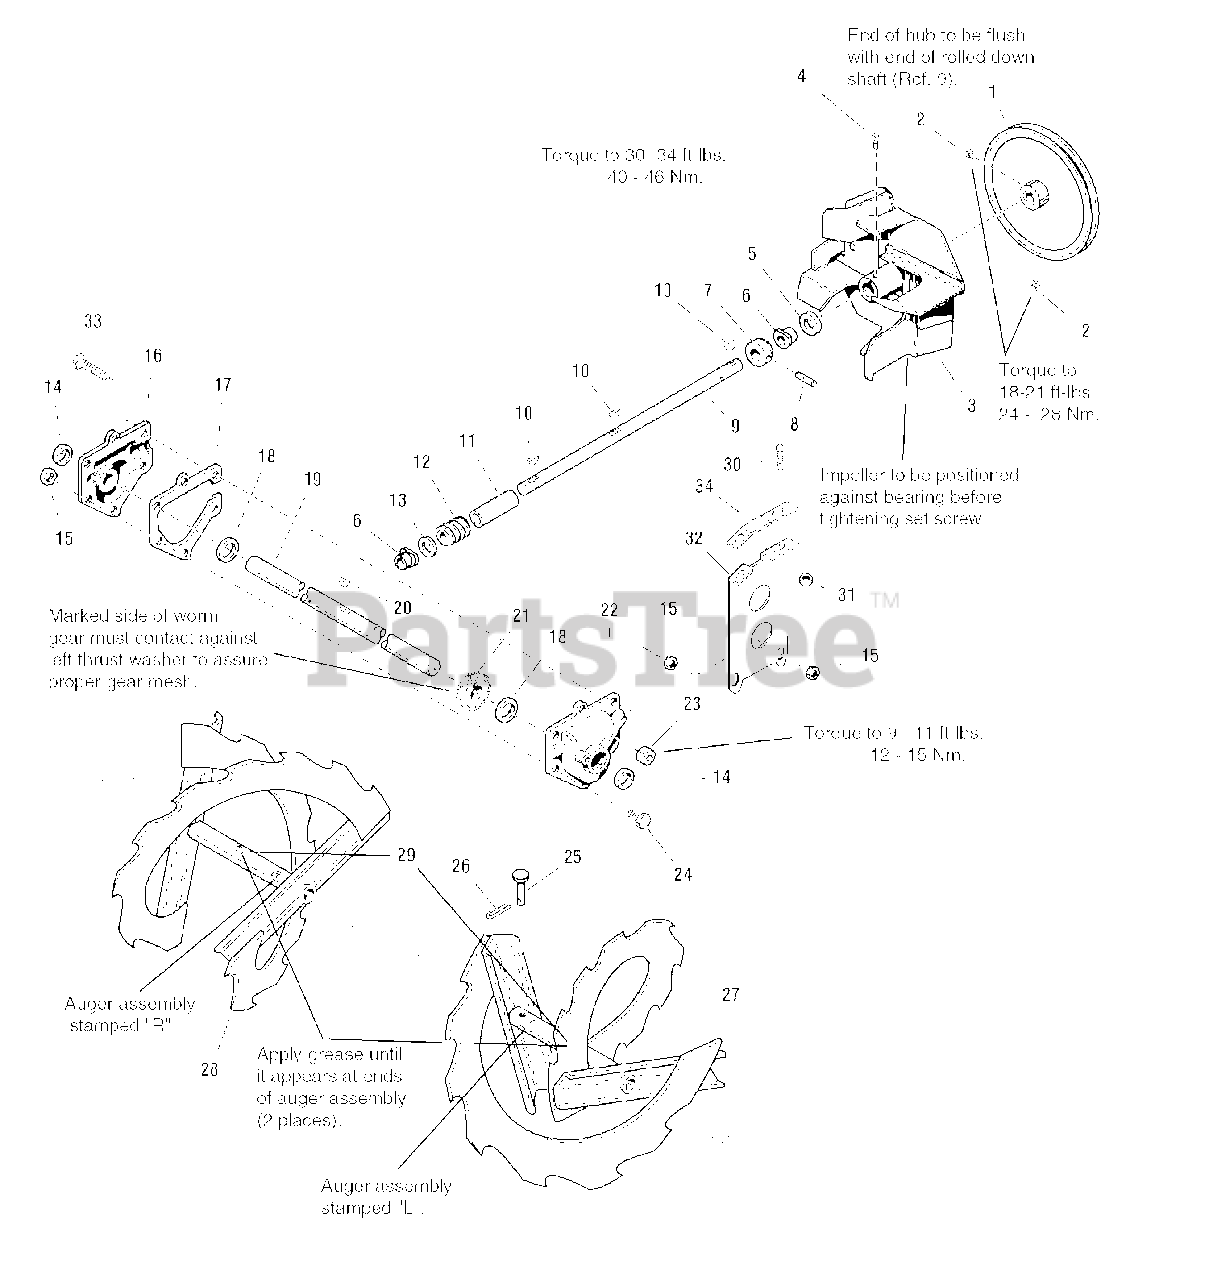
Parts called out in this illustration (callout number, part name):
1	PULLEY, Auger Input
2	SETSCREW, Square Head, 5/16-18 x 1/2
3	IMPELLER ASSEMBLY
4	SETSCREW, Square Head, 3/8-16x 1/2
6	BUSHING, Flange
7	COLLAR, Thrust
8	PIN, Drivelok, 3/16 x 1-1/2
9	SHAFT, Worm
10	KEY, Woodruff, 3/16 x 5/8
12	GEAR, Rolled Worm
13	WASHER, Thrust
15	LOCKNUT, Hex, 1/4-20
16	CASE, Gear, RH
18	WASHER, Thrust
19	SHAFT, Auger
20	KEY, Woodruff, 1/4 x 3/4
21	GEAR, Worm
22	CASE, Gear, LH
23	PLUG, Pipe, Tapered, 1/8
24	CAPSCREW, Hex Head, 1/4-20 x 7/8
25	PIN, Shear
26	PIN, Cotter, 3/32 x 3/4
27	AUGER ASSEMBLY, LH, 32"
28	AUGER ASSEMBLY, RH, 32"
29	FITTING, Lube, 1/4
30	CARRIAGE BOLT, 5/16-18 x 3/4
31	NUT, Hex Flange Whiz Lock, 5/16-18
32	SUPPORT, Gear Box
33	CAPSCREW, Hex Head, 1/4-20 x 2-1/2
34	PLATE, As Needed
